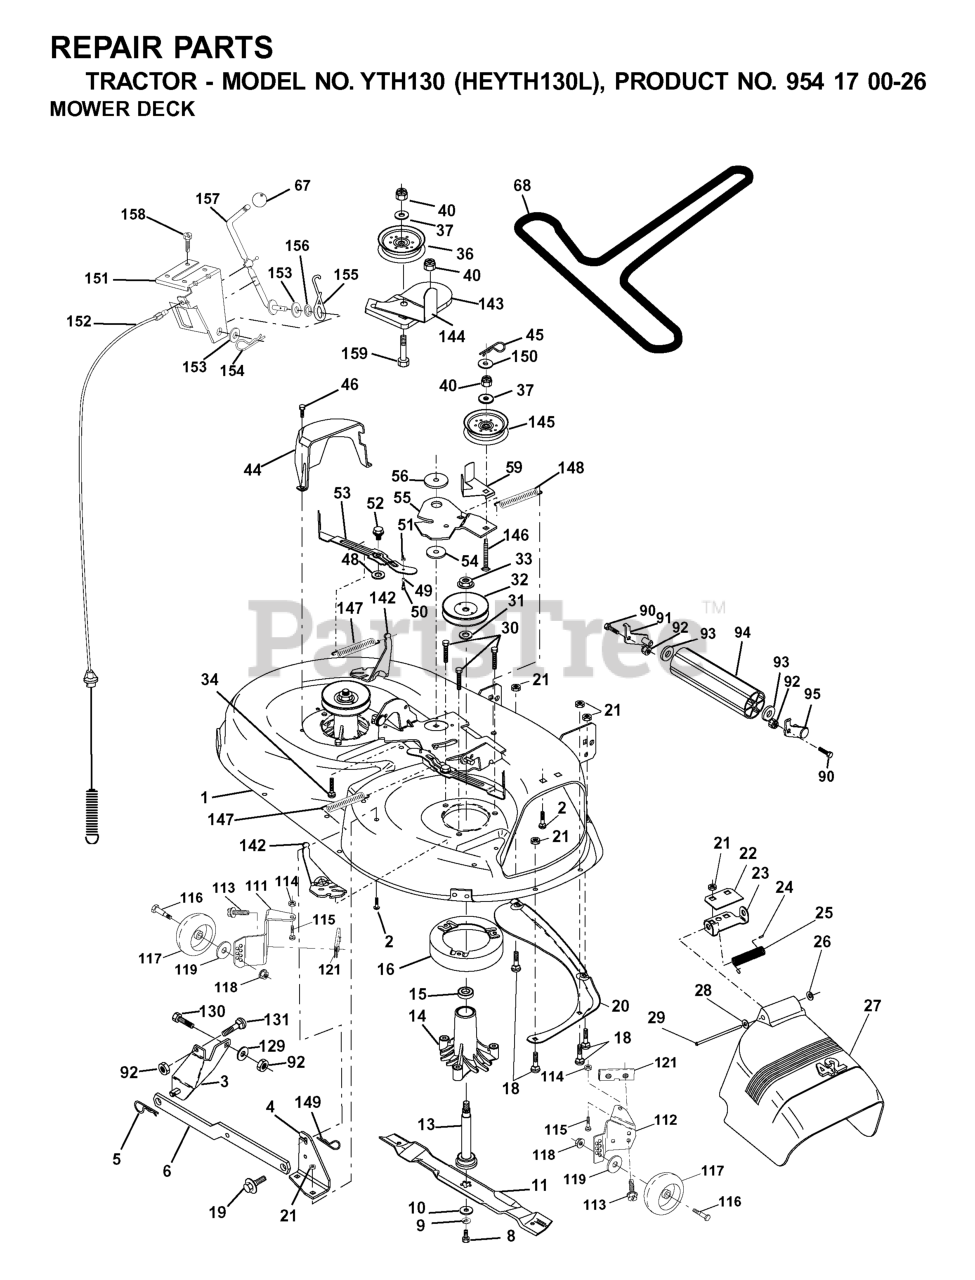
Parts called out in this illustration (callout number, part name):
1	42" DECK KIT
2	RP BOLT 5/16-18 X3/4 ZN/YEL GR
3	BRKT ASM SWAY BAR
4	BRACKET SWAY BAR 42" DECK
5	RETAINER-SPRNG RB
6	REAR SUSP ARM
8	BLADE BOLT
9	LOCKWASHER
10	WASHER.BLADE
11	Blade Mower 42" High Perf.
13	SHAFT ASM VENT
14	HOUSING, MANDREL 48"
16	STRIPPER.MANDREL.ROUND.BLACK
18	BOLT
19	BOLT SHD 5/16-18
20	BAFFLE.VORTEX
21	LOCKNUT
22	STIFFENER BRACKET
23	DEFLECTOR BRACKET
24	CAP-SLEEVE LT
25	SPRING TORSION
26	NUT PUSH M
27	SHIELD DEFLECTOR
28	Washer 11/32 x 5/8 x 16 Ga SD
29	ROD.HINGE
30	SCREW THDROL ROLLING WASHER HD
31	WASHER
32	PULLEY/MANDREL
33	NUT
36	FLAT IDLER PULLEY
37	WASHER
44	GUARD MANDREL LH BLACK
45	RETAINER M
46	SCREW.1/4-20X5/8
49	ROLLER ASM CAM FOLLOWER
52	BOLT.SHOULDER.5/16-18
53	ARM
54	HARDENED WASHER
55	ARM IDLER 42" MOWER LT/YT
56	SPACER.RETAINER.MOWER
59	GUARD, BELT
67	KNOB T (3/8 HOLE)
68	BELT V SECONDARY
90	SCREW
91	BRACKET ASM, ROLLER
92	NUT
93	Washer 1 17/32 X 7/8 X 16 Ga
94	NOSE ROLLER
95	BRACKET ASM, ROLLER (L)
111	BRACKET WHEEL GAUGE LH 42" DK
112	BRACKET WHEEL GAUGE RH 42" DK
113	Screw Tapping 5/16-18 Unc
114	NUT
115	BOLT.CARR.5/16-18X1/2
116	BOLT M
117	WHEEL.GAUGE.STANDARD
118	LOCKNUT
119	WASHER.5/16.FLAT.STE.STD.
121	BRACKET.EXTRUDED.GAGE.WHEEL
129	WASHER
131	BOLT D
142	ARM SPRING BRAKE MOWER
143	BRACKET, ARM IDLER
144	DNO KEEPER.BELT.42".CLUTCH.CBL
145	PULLEY
146	BOLT, CARRIAGE IDLER BLACK
147	SPRING EXTENSION
148	IDLER RETURN SPRING
149	SPRING.RETAINER.YELLOW.ZINC
151	BRACKET.CLUTCH.CABLE
152	CLUTCH CABLE 42"
153	WASHER FLAT 3/8"
154	SPRING RETAINER
155	SPRING RETENTION LEVER
156	SPACER.CLUTCH.CABLE
157	ROD CLUTCH CABLE 3/8"
158	SCREW LT
